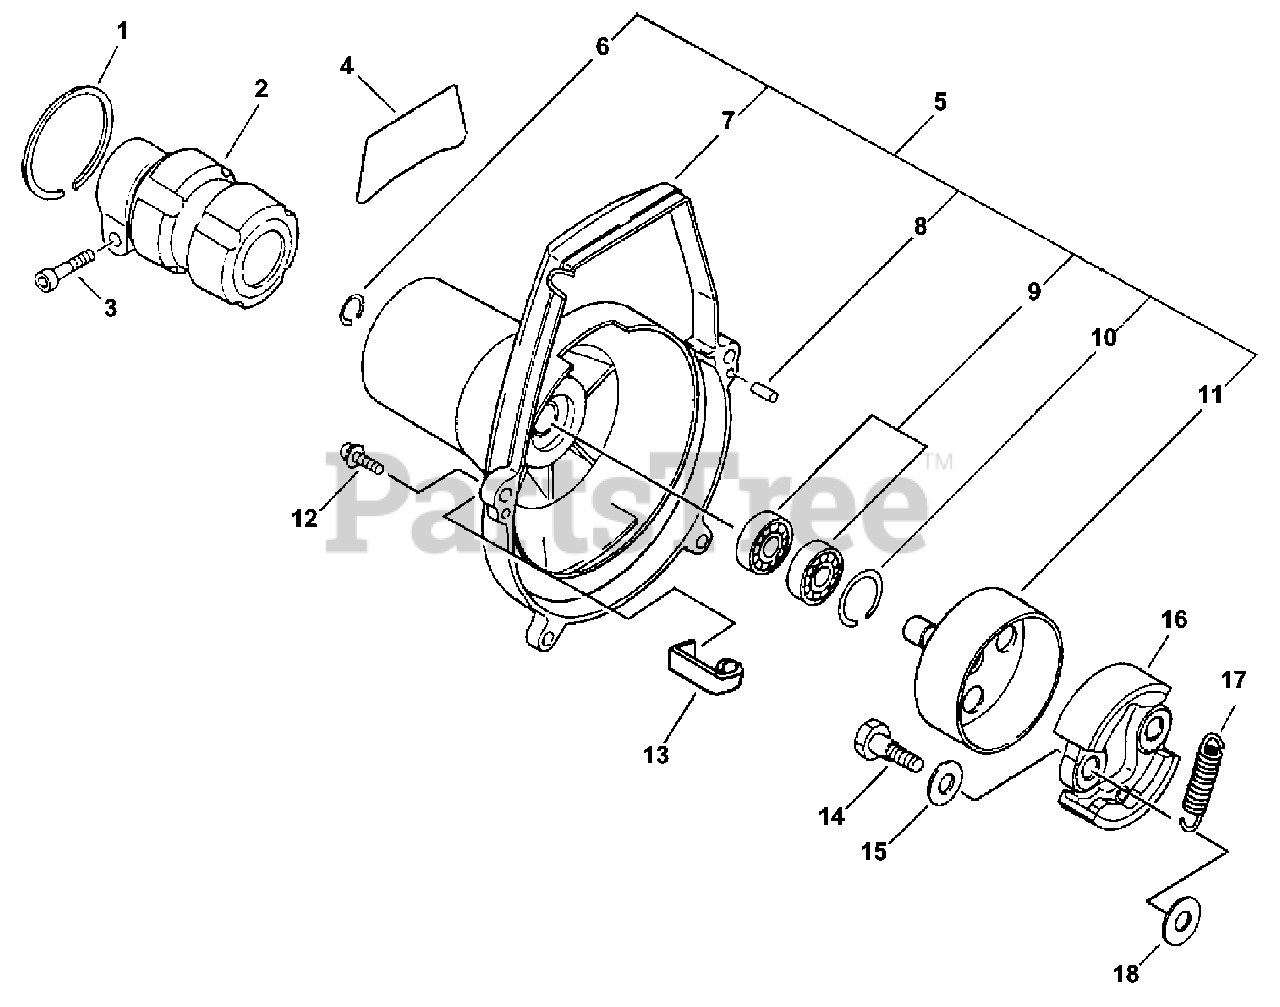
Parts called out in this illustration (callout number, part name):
1	RING, RETAINING - 42
2	CLAMP, MAIN PIPE
3	SCREW - 5X28
4	LABEL - MODEL PAS-230
4	LABEL - MODEL PAS-231
5	FAN CASE ASSY - GRAY
6	RING, RETAINING - 12
7	CASE, FAN - GRAY
8	PIN - LOCATING
9	BEARING, BALL - 6001
10	RING, RETAINING - 28
11	DRUM, CLUTCH
12	SCREW - 5X18
14	BOLT, CLUTCH
15	WASHER - SPRING
16	SHOE, CLUTCH
17	SPRING, CLUTCH
18	WASHER - 6
